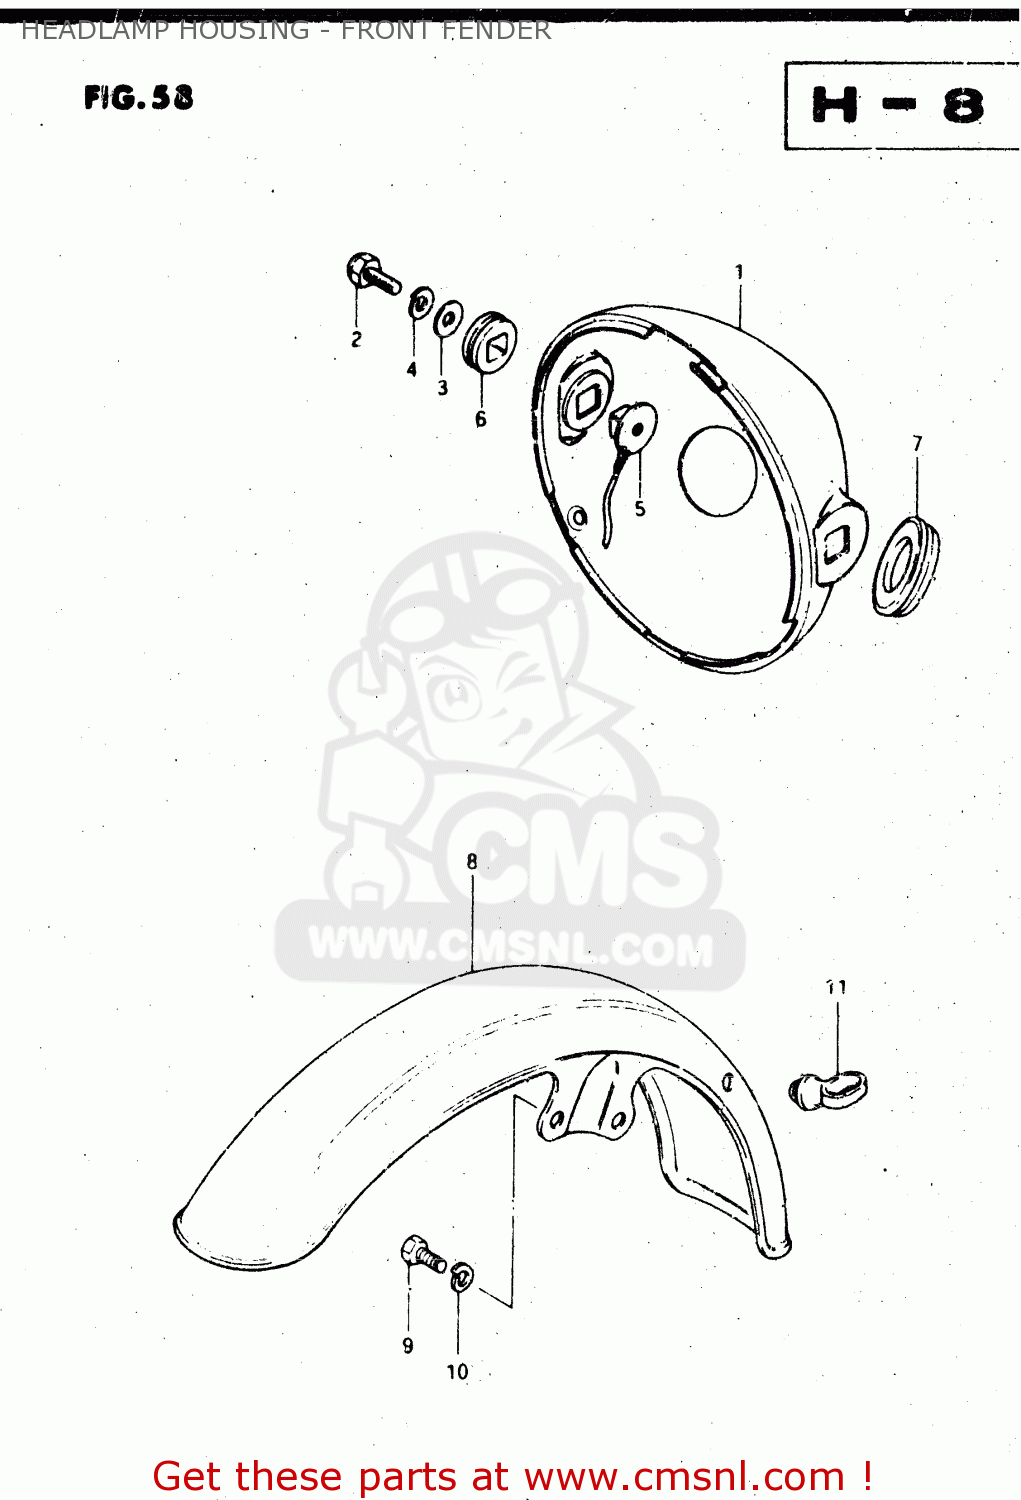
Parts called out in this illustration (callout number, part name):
1	HOUSING,HEADLAMP
2	BOLT
3	WASHER
4	LOCK WASHER
5	SPACER,HEADLAMP HOUSING
6	CUSHION,HEADLAMP HOUSING
7	GROMMET,HEADLAMP HOUSING
8	FENDER,FR
9	BOLT
10	LOCK WASHER
11	GUIDE,CABLE
